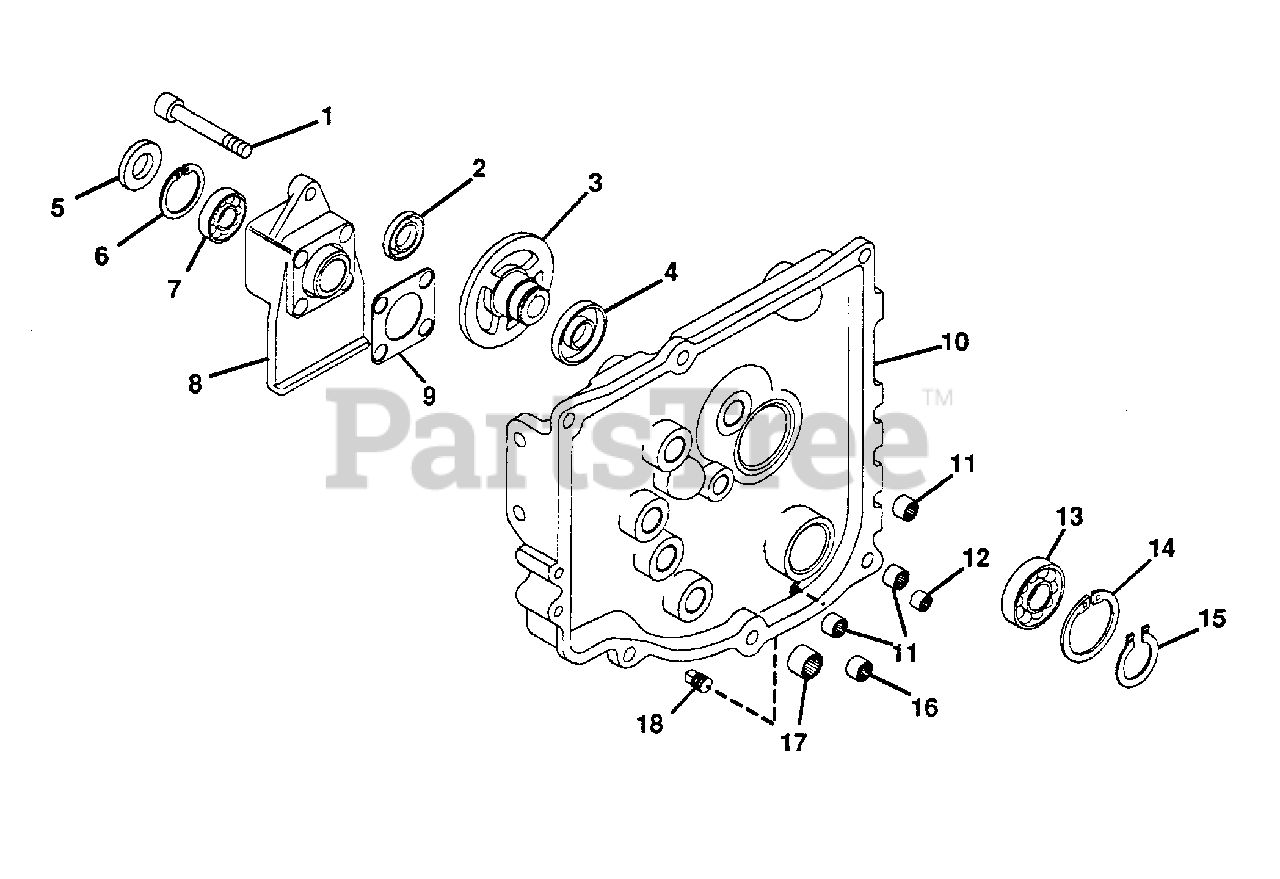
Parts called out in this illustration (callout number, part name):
1	BOLT, HEX 1/2-13X3.25
2	SEAL, OIL .750X1.625X.250
3	HUB, CLUTCH
4	SEAL, OIL 2.250X3.005X.375
5	SEAL, OIL AXLE
6	RING, RETAINING .08 THICK
7	BEARING, BALL 1.250X2.250X.500
8	RETAINER, AXLE BEARING
9	GASKET
10	ASSEMBLY, TRANSMISSION COVER
11	BEARING, NEEDLE .75X1X.75
12	BEARING, NEEDLE .625X.812X.75
13	BEARING, BALL 1.968X3.149X.629
14	RING, RETAINING 3.156 BORE
15	RING, RETAINING 1.969 SHAFT
16	BEARING, NEEDLE .75X1X.75
17	BRG, NEEDLE 1.000X1.250X.750
18	PLUG, PIPE 3/8
